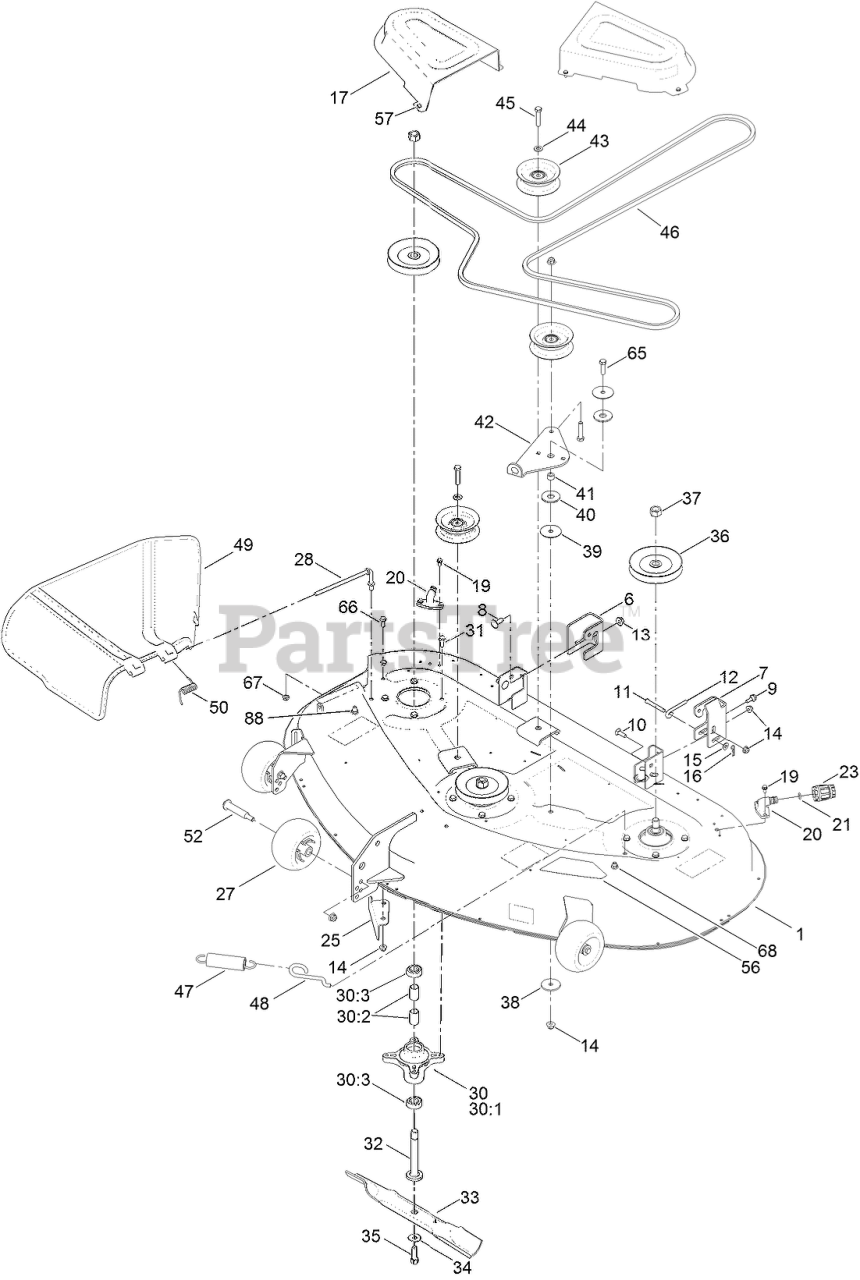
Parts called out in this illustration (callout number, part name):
1	50 INCH DECK AND DECAL ASM
6	BRACKET-HANGER, RH
7	BRACKET-HANGER, LH
8	BOLT-CARR
9	SCREW-SHOULDER, HHF
10	SCREW-CARR
11	PIN-CLEVIS
12	ROD-LEVEL, DECK
13	NUT-HF, NI
14	NUT-HF, NI
15	WASHER-PLAIN
16	PIN-COTTER
17	COVER-BELT
19	SCREW-HWH
20	FITTING-WASHOUT
21	O-RING
23	CONNECTOR-HOSE
25	BAFFLE-CUTOFF
27	ROLLER-SCALP, ANTI
28	ROD-PIVOT
30	SPINDLE ASM
30:1	SPINDLE
30:2	SPACER
30:3	BEARING-BALL
31	SCREW-TAPTITE
32	SHAFT-SPINDLE
33	BLADE-HI LIFT
34	WASHER-BELLEVILLE
35	SCREW-HH
36	PULLEY
37	NUT-HEX
38	WASHER-REBOUND
39	WASHER
40	WASHER-FRICTION, COMPOSITE
41	SPACER
42	ARM-IDLER
43	PULLEY-IDLER, FLAT
44	WASHER-FLAT
45	SCREW-HH
46	V-BELT
47	SPRING-EXTENSION
48	HOOK-RETURN, SPRING
49	DEFLECTOR
50	SPRING-TORSION
52	BOLT-SHOULDER
57	SCREW-TAPTITE
65	SCREW-HH
66	SCREW-HH
67	NUT-LOCK, NI
68	SCREW-HH
88	SCREW-CARR
